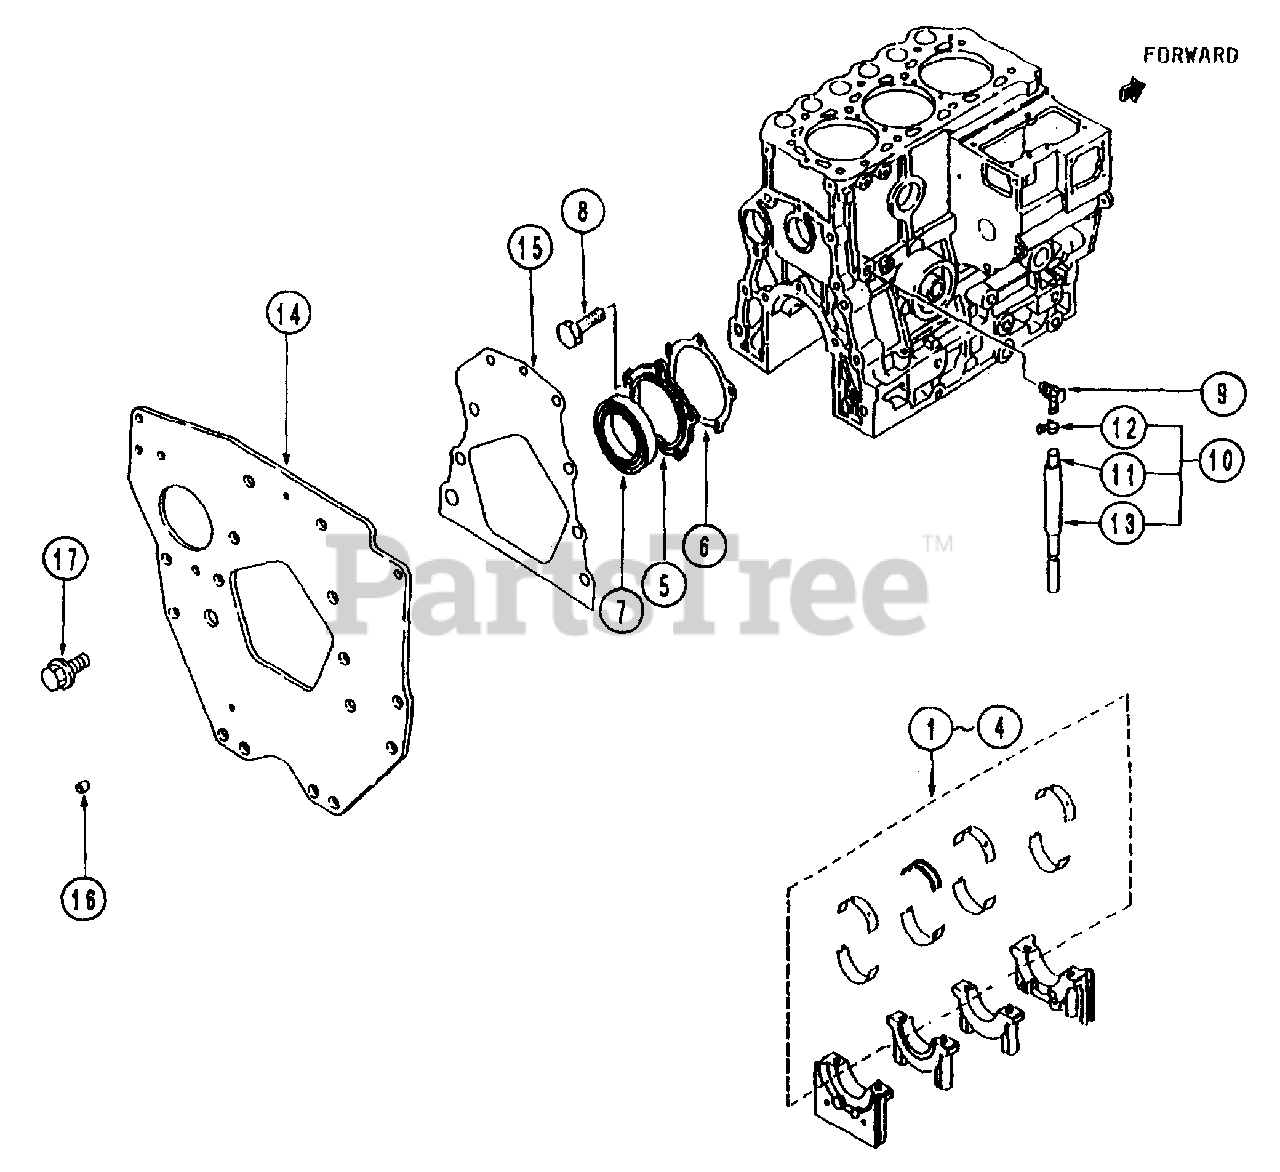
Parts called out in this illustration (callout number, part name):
1	Metal Set
2	Metal Set
3	Metal Set
4	Metal Set
5	Case, Oil Seal
6	Gasket, Oil Seal Case
9	Joint, Water Drain
10	Hose Ass'y., Water
14	Plate, Rear
15	Gasket, Rear Plate
17	Bolt, Flange
